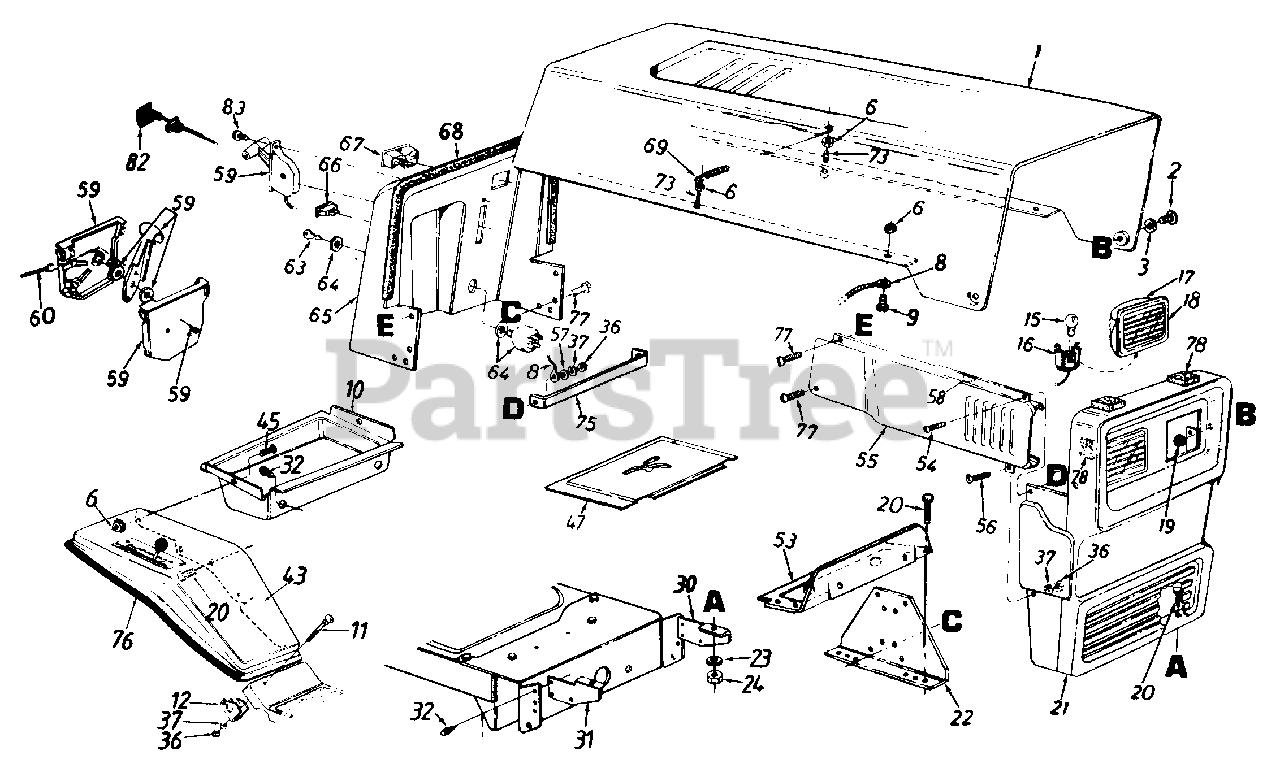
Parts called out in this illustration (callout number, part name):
3	Washer.39" I.D. x.62"
6	Hex Sems Nut #10-24 Thd.
8	Hood Stop
9	Truss Hd. Scr. #10-24 x 1/2"
10	Tool Tray
11	Carriage Bolt 1/4-20 x 2" Lg.
12	Fender Clamp
15	Lamp
16	Twist Lock-Lamp Socket
17	Headlight Housing
18	Lens
19	L-Nut 1/4-28 Thd.
20	Hex Bolt 5/16-18 x .75" Lg.
23	L-Wash. 5/16" I.D.
24	Hex Nut 5/16-18 Thd.
30	Grille Mount Brk't.-L.H.
36	Hex Nut '4-20 Thd.*
37	L-Wash. 1/4" I.D.
43	Fender
47	Transmission Panel
53	Fuel Tank Support
54	Truss Hd. Scr. 1/4-20 x .75"
55	Side Cover-R.H.
57	Fl-Wash. .281" I.D. x .73" O.D.
58	Mounting Clamp
59	Throttle Control Box Ass'y.
60	Throttle Control Wire
63	Ignition Key
64	Ignition Switch
67	Ammeter
68	Trim Strip-31"
69	Hood Spring
73	Hex Scr. #10-24 x 1.0" Lg.
75	Tie Strap-Grille/Side Panel
76	Trim Strip-57"
77	Hex Wash. Hd. Tap Scr. 1/4 x .75" Lg.
78	Foam Strip 3/8 x 1-1/8" x 11/2" Lg.
82	Choke Control 29" Lg.
83	Truss Mach. AB-Tap Scr. #10 x .5" Lg.
